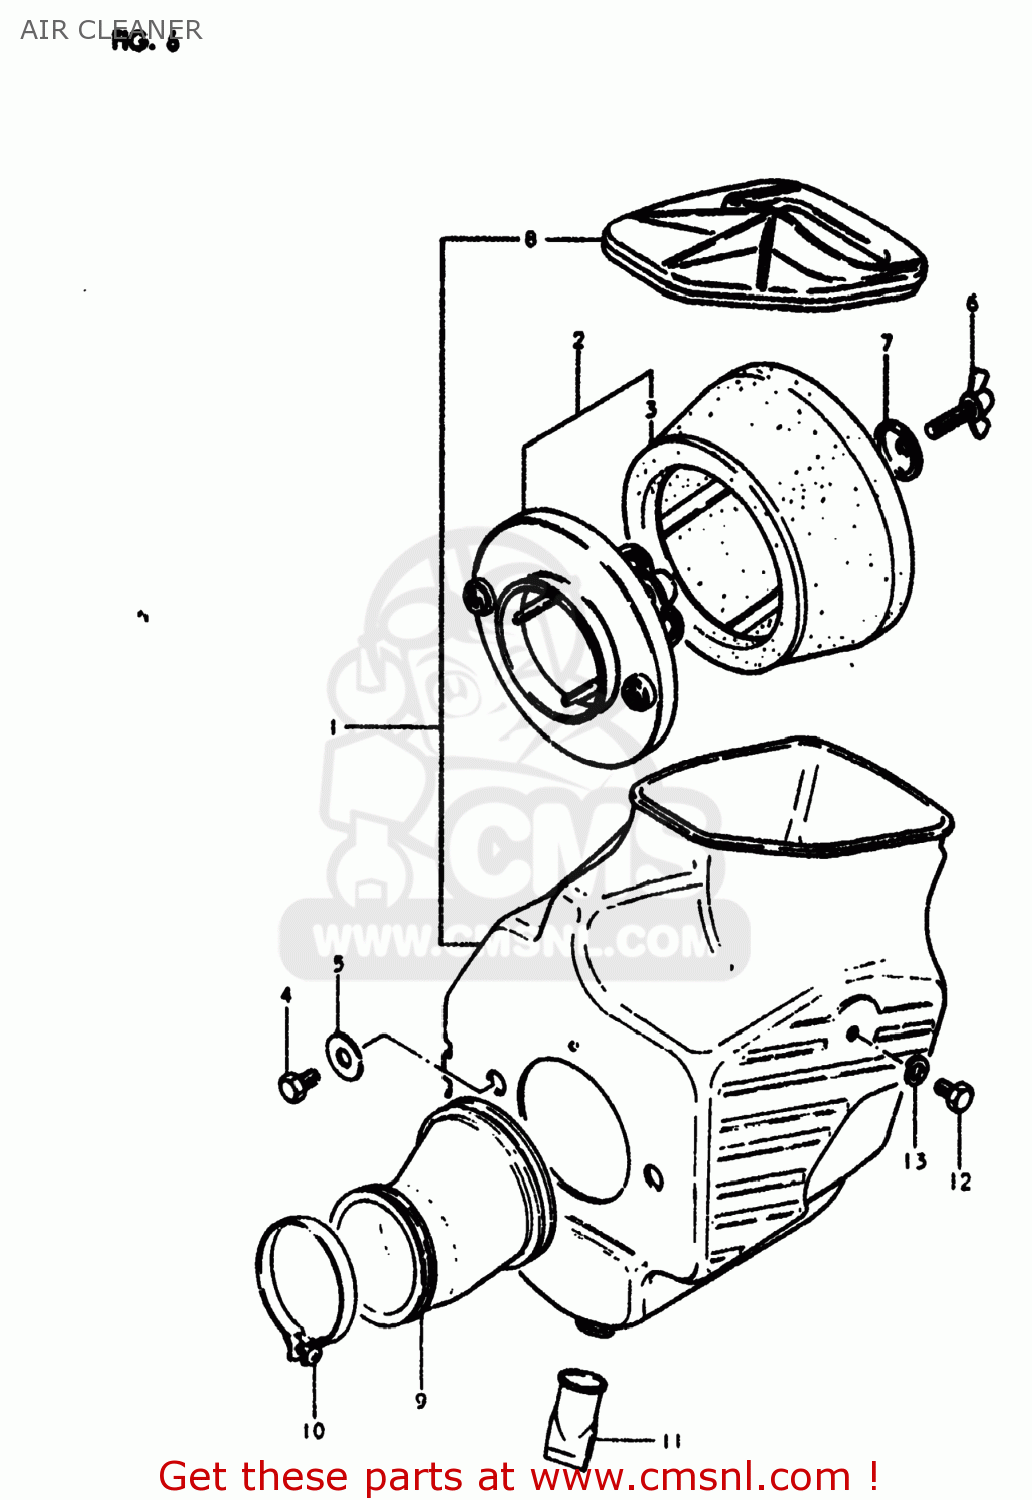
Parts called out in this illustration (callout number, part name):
1	CLEANER ASSEMBLY,AIR
2	FILTER,AIR CLEANER
3	FILTER
4	BOLT
5	SPACER,AIR CLEANER,REAR
6	WING BOLT,AIR CLEANER
7	HOLDER,FILTER
8	CAP,AIR CLEANER
9	TUBE,AIR CLEANER OUTLET
10	CLAMP
11	HOSE,AIR CLEANER DRAIN
12	BOLT
13	LOCK WASHER
